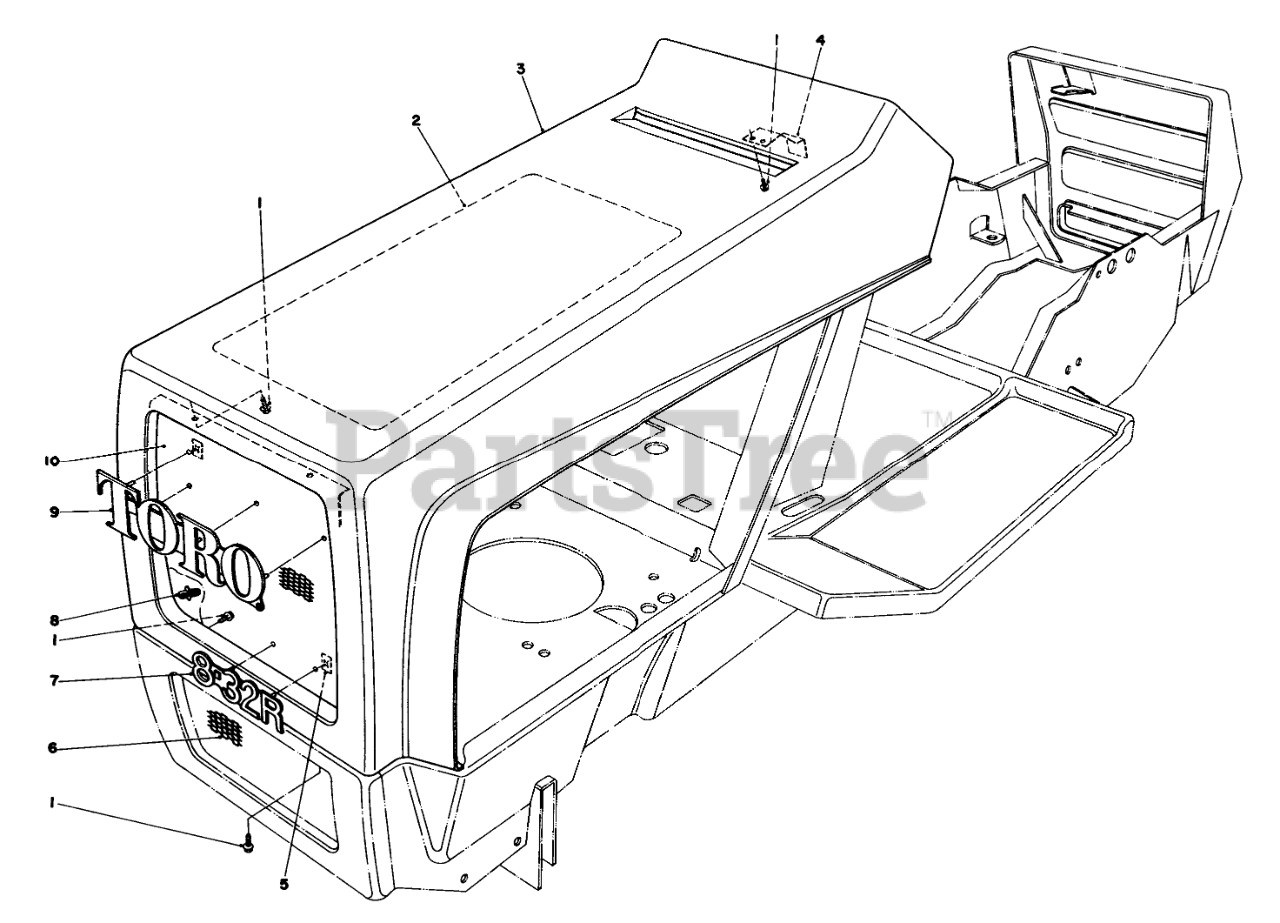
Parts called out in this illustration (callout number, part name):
1	SCREW-HWHTF
2	Decal-Service
4	SPRING LATCH
6	LOWER GRILLE
7	Name Plate Grille
8	HINGE BRKT STUD
9	Logo-Grille
10	Grille Hood
